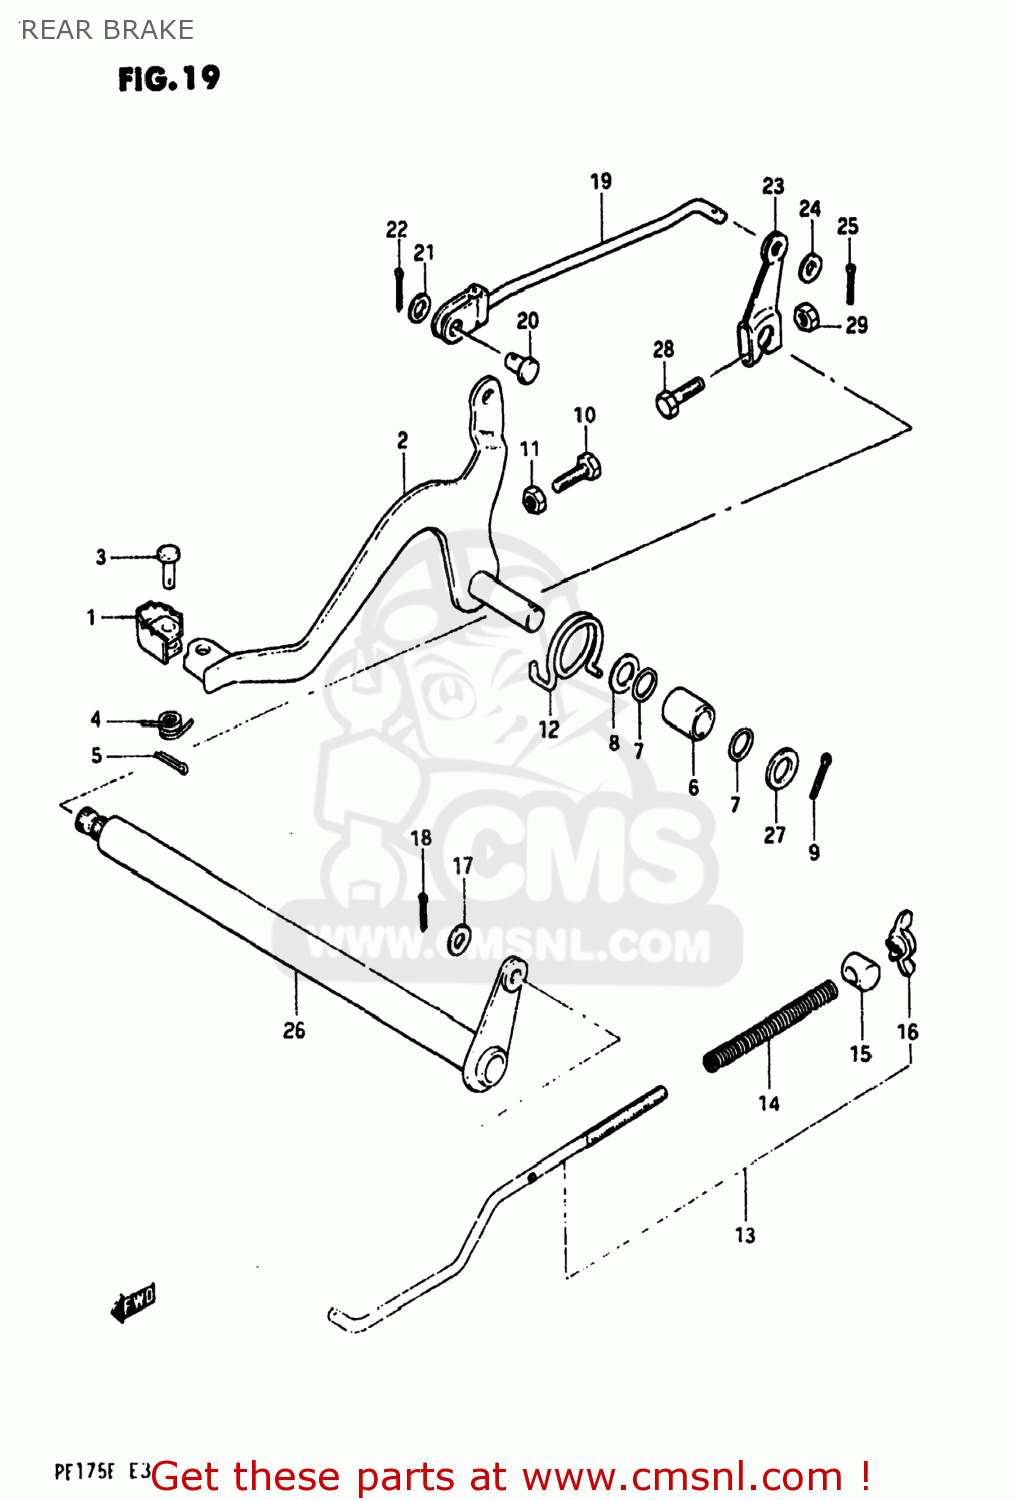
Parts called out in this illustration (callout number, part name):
1	PEDAL,BRAKE
2	ARM,BRAKE PEDAL
3	PIN
4	SPRING
5	PIN
6	BUSHING
7	O RING(D:2.2,ID:11.8)
8	WASHER
9	PIN 30X20
10	BOLT(6X23)
11	NUT
12	SPRING
13	ROD ASSEMBLY,REAR BRAKE,REAR
14	SPRING
15	PIN
16	NUT
17	WASHER
18	PIN 20X20
19	ROD ASSEMBLY,REAR BRAKE FRONT
20	PIN(L:13.5)
21	WASHER
22	PIN 20X20
23	ARM,REAR BRAKE ROD,OUTER
24	WASHER
25	PIN 20X20
26	ARM,REAR BRAKE ROD
27	WASHER(12.1X30X2.3)
28	BOLT
29	NUT
